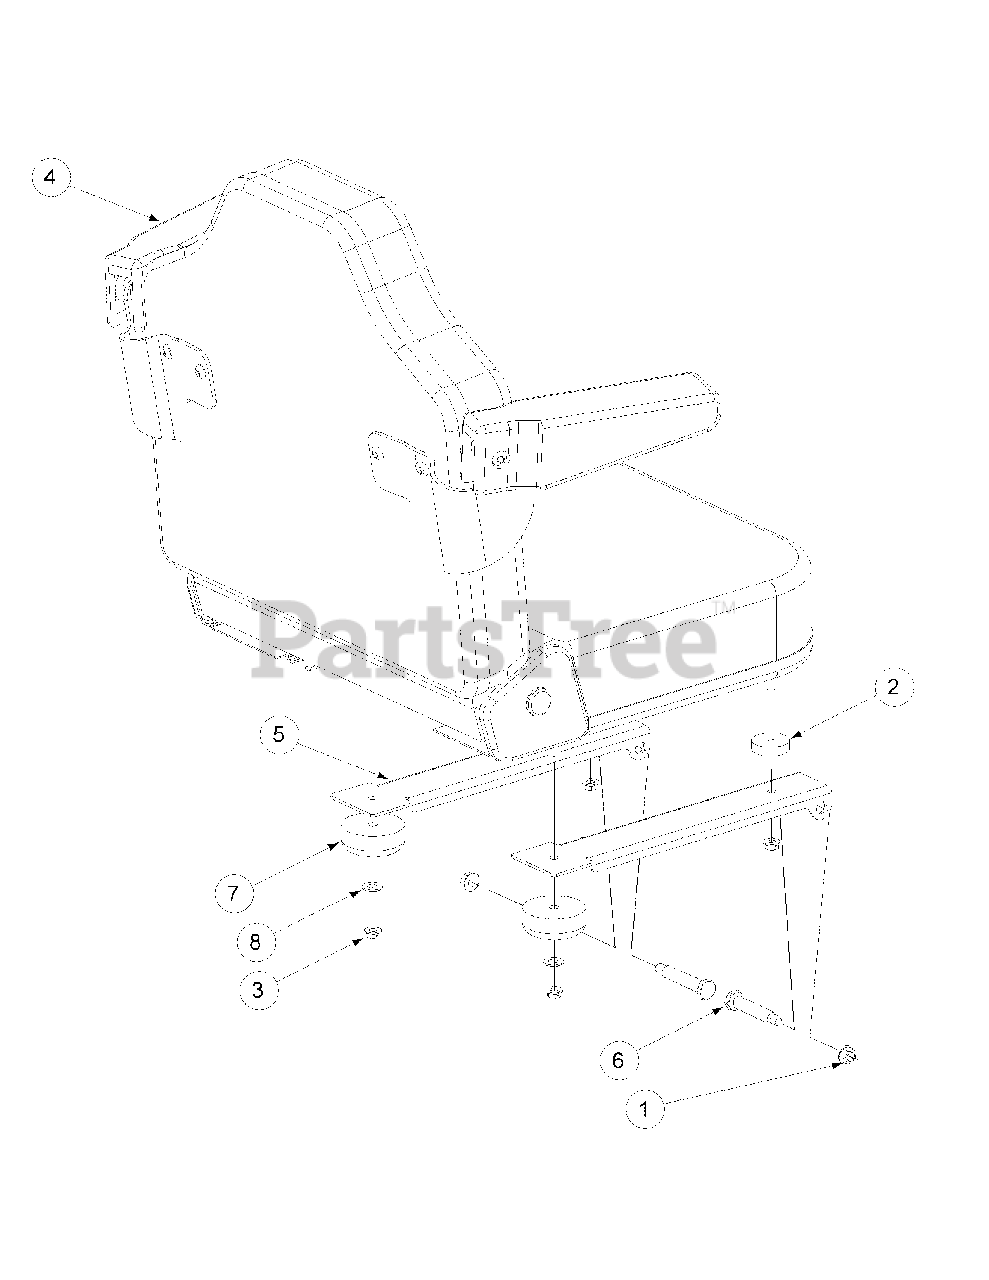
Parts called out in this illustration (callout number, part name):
1	Nut, Hex 3/8-16 Flange Lock
2	Spacer, 0.406 ID x 1.00 OD x .38
3	Lock Nut, Hex Flange, 5/16-18
4	Adjustable Seat, Black embossed, Forward Fold
4	Armrest kit
5	Mounting Bracket, Seat
6	Shoulder Screw, .50x2.345, 3/8-16
7	Grommet, 2.5 OD x 1.0 Long
8	Washer
